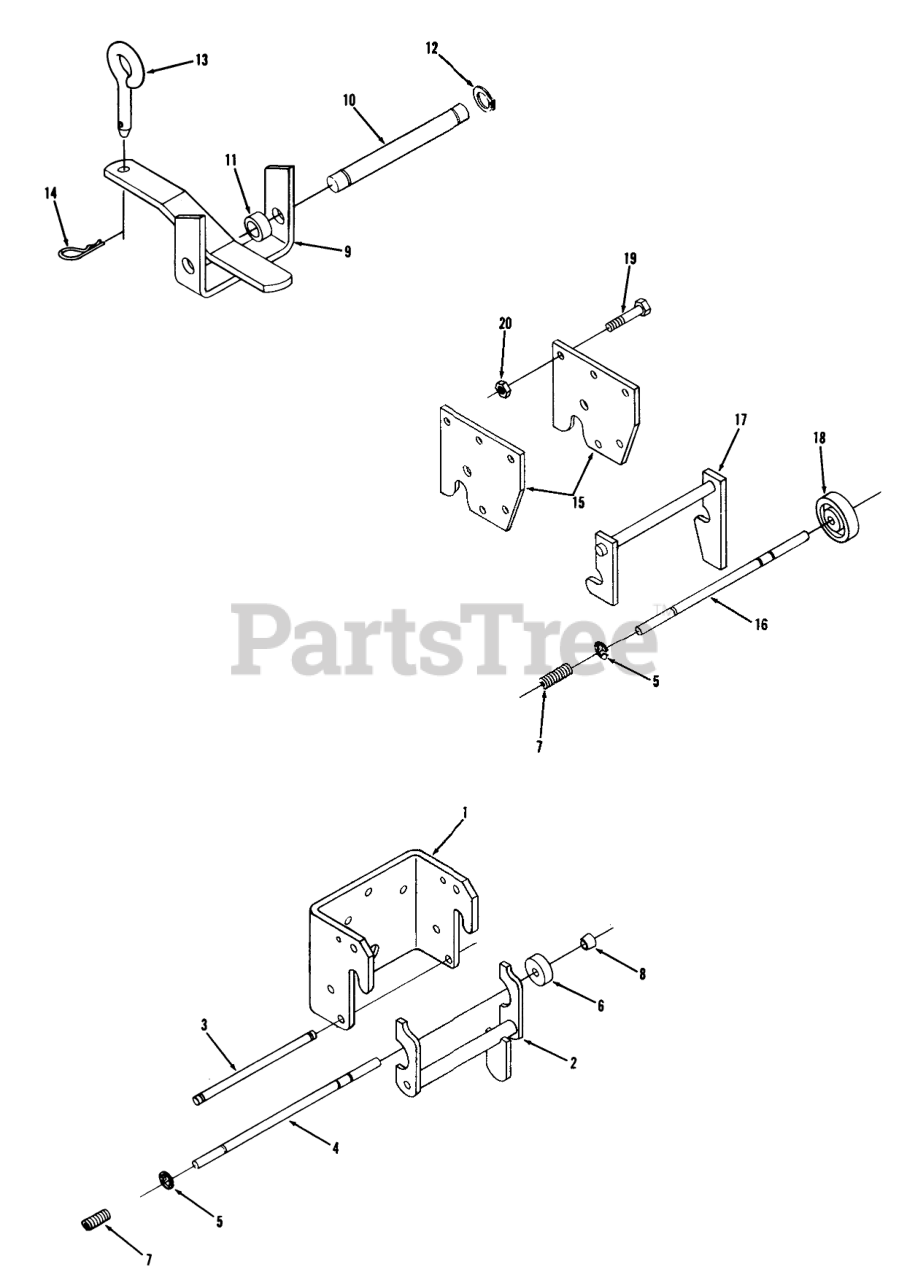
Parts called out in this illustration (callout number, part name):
1	Front Hitch
2	Assy-Latch
3	ROD-LATCH PIVOT
4	ROD-LOCK
5	RING-RETAINING
7	SPRING
8	CAP-ROD, PLUNGER
9	Hitch
10	PIN-STATIONARY HITCH
11	Spacer
12	E-RING
13	Pin-Tool
14	Hairpin Cotter
15	Hitch Plate
17	ASSY MID HITCH LA R
19	BOLT
20	Nut
